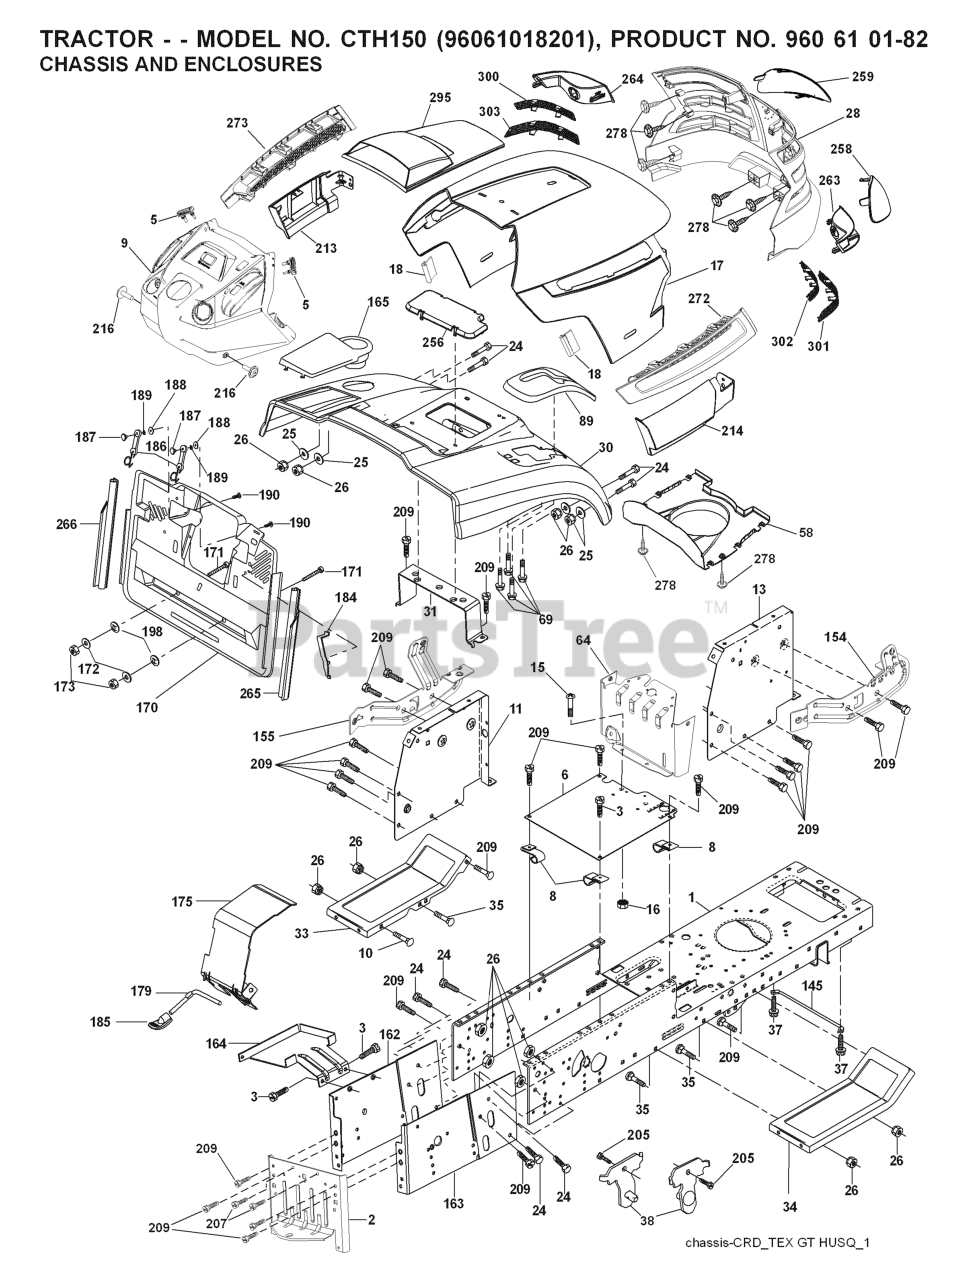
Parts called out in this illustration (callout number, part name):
2	DRAWBAR
3	SCREW 3/8-16X3/4
5	BUMPER DASH
6	PLATE
8	CLIP,INSULATOR
10	BOLT D
11	PANEL DASH LH
13	PANEL DASH RH
15	Screw, Machine, Truss Head 5/16-18 UNC x 3/4
16	NUT
17	HOOD
18	BUMPER.HOOD.TEX.HUSQVARNA
25	WASHER
26	NUT
28	GRILL.ASM.HUSQ.TG/CRD.W/TRIM
30	CONSOLE.CRD.AUTO.GRY
31	BRACKET SUPPORT FENDER
33	FOOTREST PNT LH
34	FOOTREST PNT RH
37	Screw 5/16-18 x 1/2 Hex, Self Tapping 5/16-18 x 1/2
38	BRACKET ASM PIVOT MOWER REAR
58	AIR.DUCT.TEXGT.HUSQ.31
69	SCREW.HI-LO.CONSOLE
89	CONSOLE.CRD.AUTO.GREY.2005
145	ROD.PIVOT.HOOD
162	BRACKET
163	BRACKET EXTEN CHASSIS RH CRD
165	RP.COVER.BATTERY.CRD.GREY
172	WASHER
175	DOOR TRAP
179	ROD PIVOT FBI
184	BRACKET.ACTUATOR.BAGGER.SRD
186	LATCH ASSY
187	WELDNUT
189	LOCKWASHER #10
190	SCREW
207	SCREW, 5/16-18 X 1/2
209	SCREW, 3/8-16X3/4
213	SKIRT.HOOD.SIDE.HUSQ.LH.GREY
214	SKIRT.HOOD.SIDE.HUSQ.RH.GREY
216	SCREW 14-20 X 5/8
256	COVER FENDER CRD
258	LENS.RH.TEX.GT.HUSQ.CL
259	LENS.LH.TEX.GT.HUSQ.CL
263	BEZEL.RH.TEX.GT.HUSQ
264	BEZEL.LH.TEX.GT.HUSQ
265	SEALING
266	SEALING
272	VENT.SIDE.HOOD.HUSQ.RH.GREY
273	VENT.SIDE.HOOD.HUSQ.LH.GRAY
278	SCREW
295	VENT.ASM.HOOD.TOP.TEX.
300	INSERT.HEX.GRILL.HUSQ.
301	INSERT.HEX.GRILL.HUSQ.GREY
302	INSERT.HEX.GRILL.HUSQ.
303	INSERT.HEX.GRILL.HUSQ.
